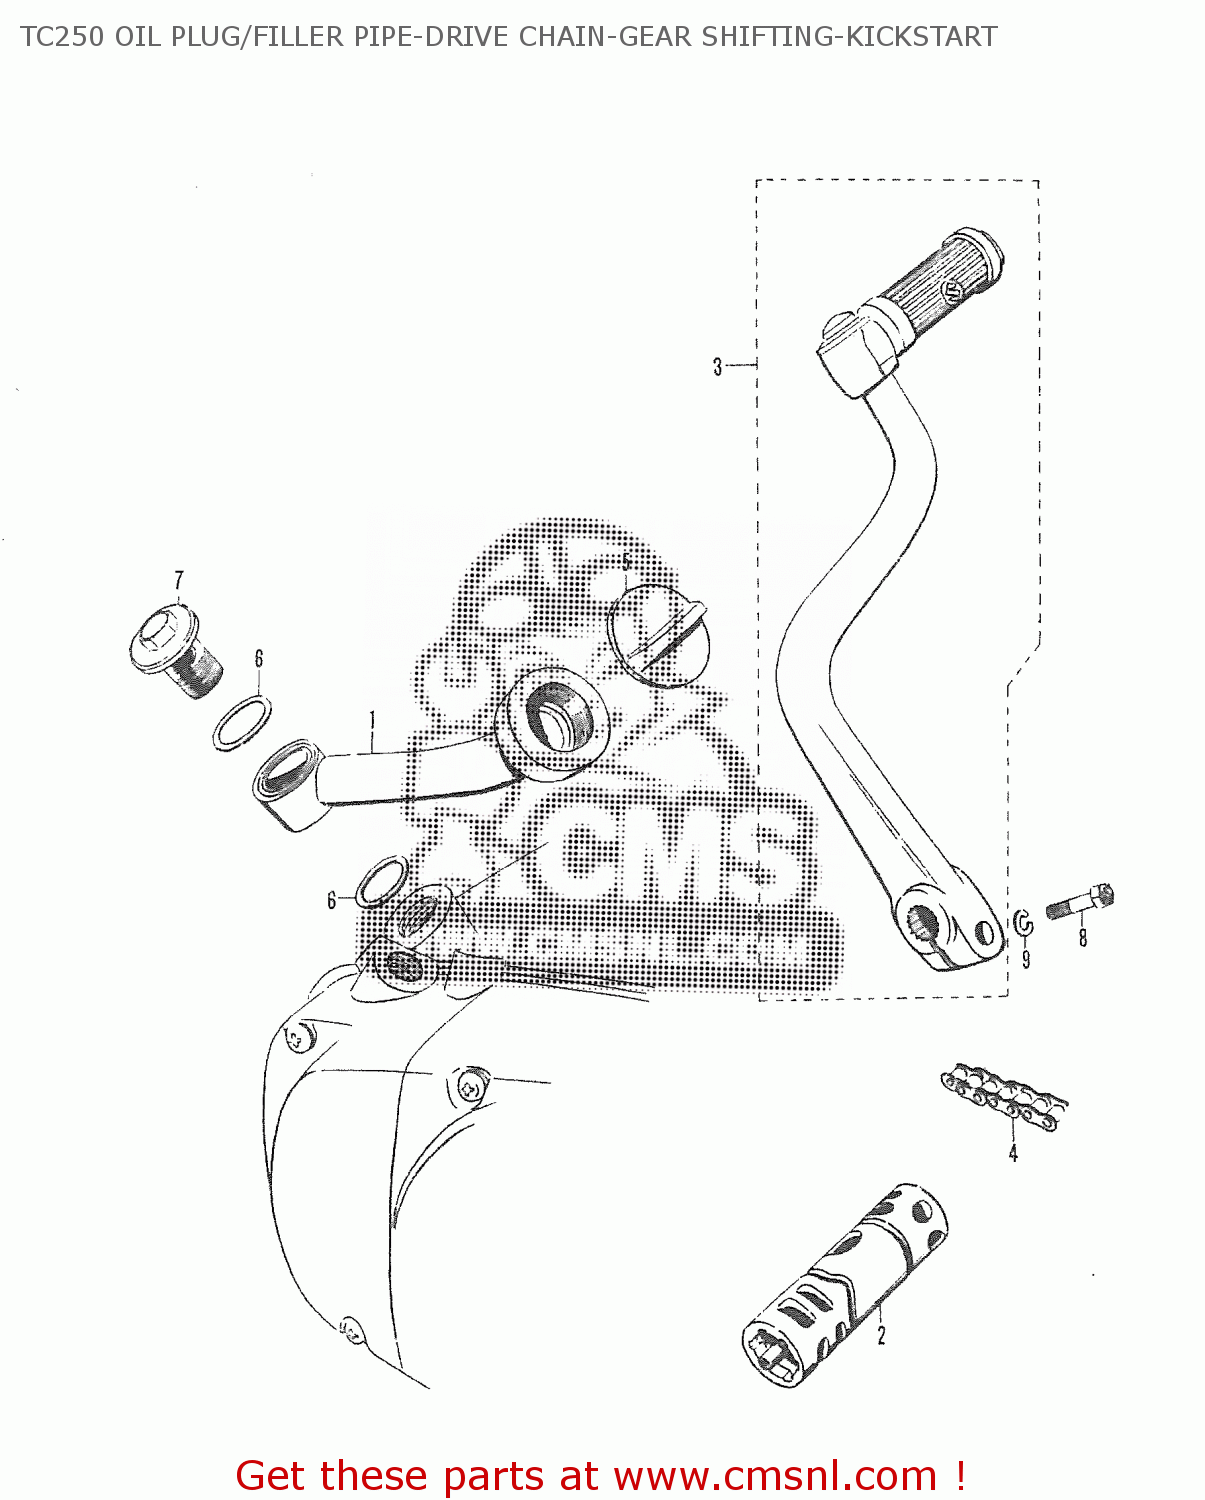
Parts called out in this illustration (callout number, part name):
1	OIL FILLER PIPE
2	GEAR SHIFTING CAM COMP
3	KICK START LEVER ASS'Y
4	CHAIN ASSEMBLY,DRIVE
5	OIL PLUG
6	O RING(D:2.4,ID:21.8)
7	OIL FILLER PIPE JOINT
8	STRONG SMALL HEAD HEXAGON BOLT
9	LOCK WASHER
